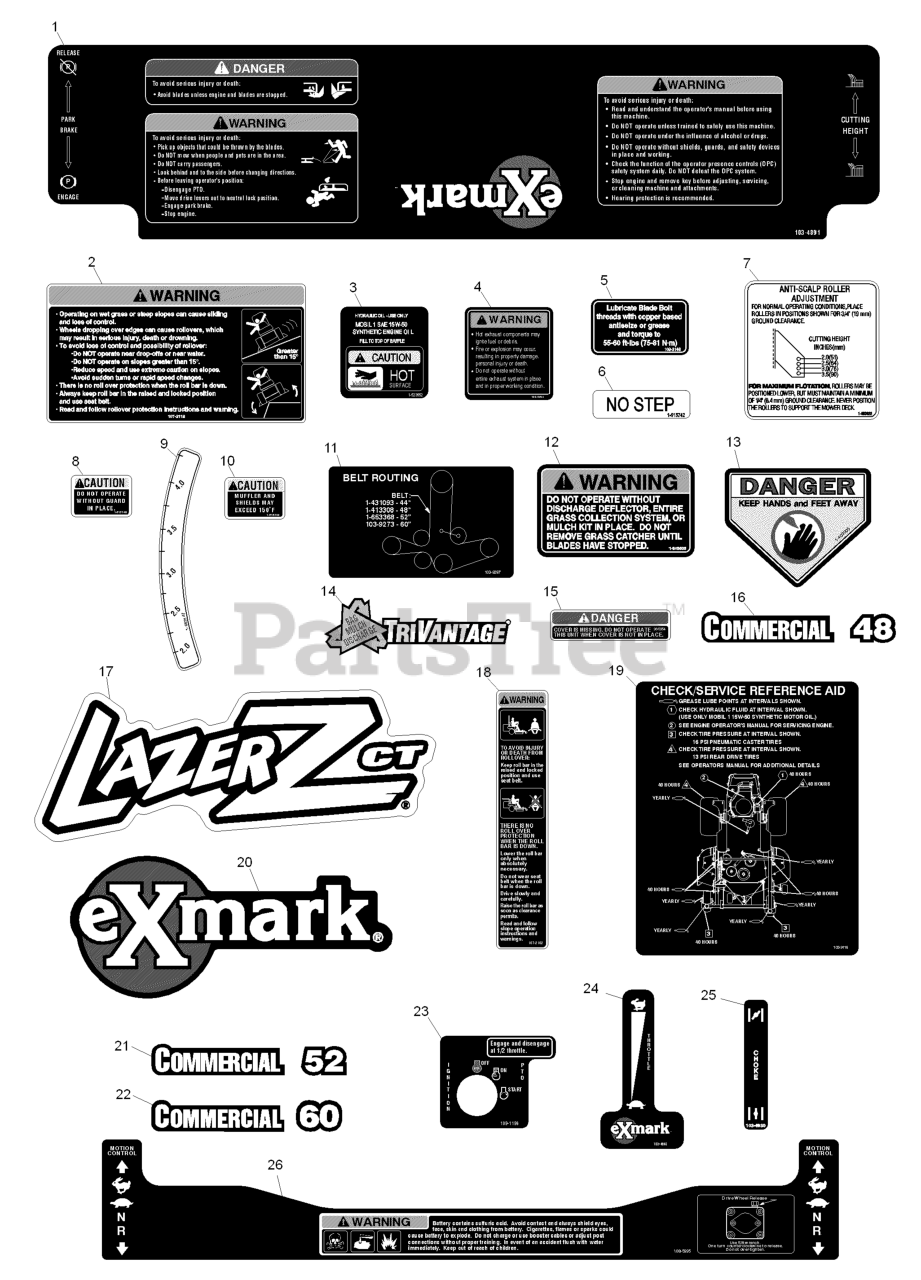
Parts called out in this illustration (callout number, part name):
1	DECAL,CONSOLE LHP
2	DECAL-WARNING
4	DECAL-EXHAUST
5	DECAL,BOLT TORQUE
6	DECAL,NO STEP
7	DECAL,ANTISCALP
8	DECAL-GUARD
9	DECAL-DECK HEIGHT, INNER
11	DECAL, BELT ROUTING
12	DECAL-WARNING, DISCHARGE
13	DECAL-DANGER
15	DECAL-COVER, MISSING
16	DECAL,COMMERCIAL 48
17	DECAL,LCT MODEL
18	DECAL-WARNING, FOLDING RO
19	DECAL, CHECK/SERVICE LCT
20	DECAL,EXMARK LOGO
21	DECAL,COMMERCIAL 52
22	DECAL,COMMERCIAL 60
23	DECAL,IGNITION/PTO
24	DECAL,THROTTLE
25	DECAL,CHOKE
26	DECAL-WARNING
